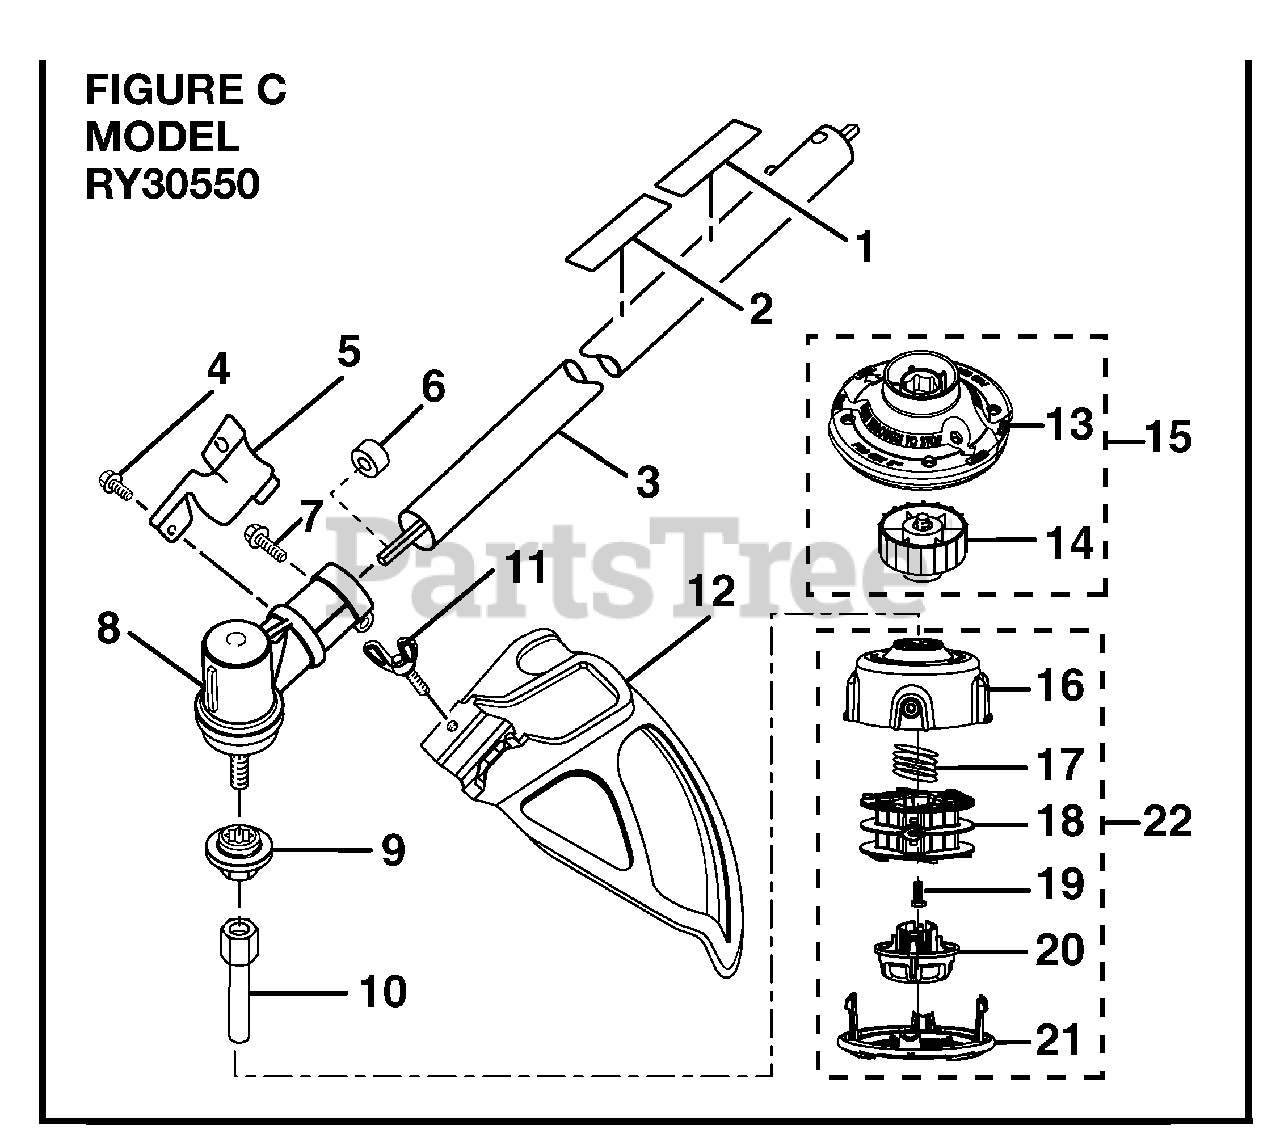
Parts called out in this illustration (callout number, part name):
1	Expand-it Label
2	Warning Decal
3	Straight Shaft Assembly
4	Screw
5	Clamp
7	Screw
8	Gear Head
9	Flanged Washer
11	Wing Screw
12	Grass Deflector Assembly
13	Pro Cut II String Head
14	Spool Retainer
15	Pro Cut II String Head Assembly
16	Housing
19	Bolt
22	Reel Easy String Head Assembly
